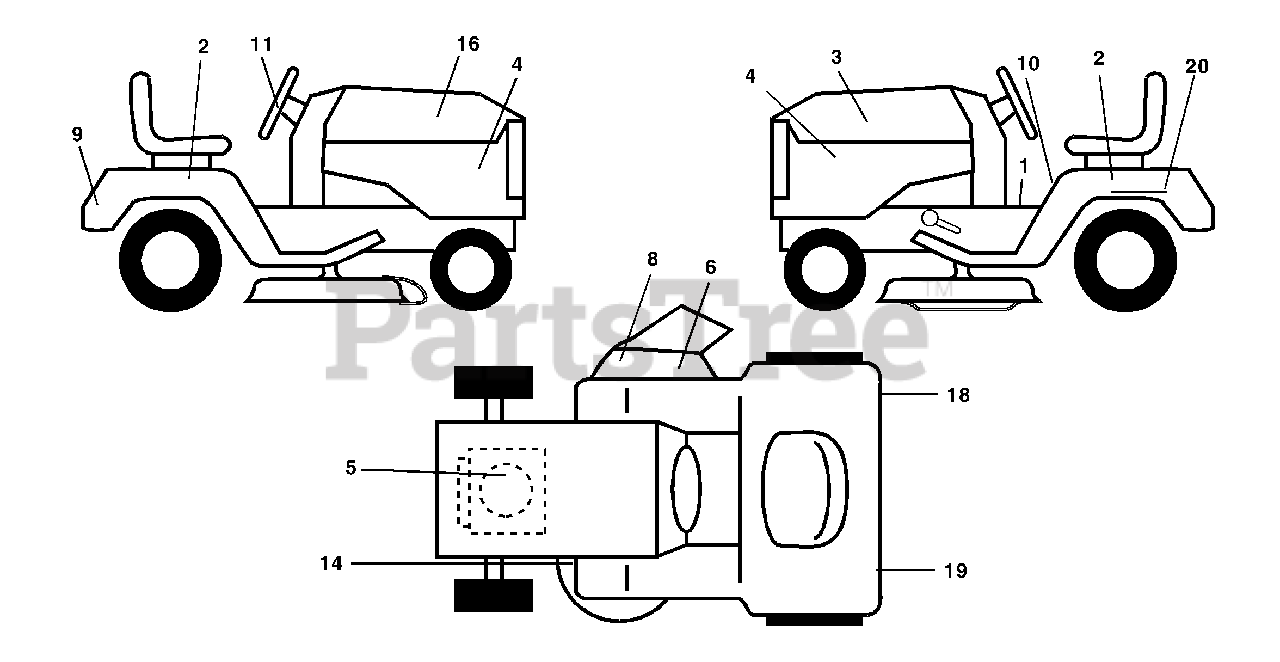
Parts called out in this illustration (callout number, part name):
2	Decal Fender Side
3	Decal Hood LH
4	Decal Side Panel Logo
5	Decal HP Engine
6	Decal Deck "B" 42"
8	Decal Warning Mult-Language
9	Decal Fender Logo
10	Decal Fender Danger E/F
11	Decal Ins Strg Whl
14	Decal V-Belt Schematic
16	Decal Hood Rh
18	Decal Fender Reflector RH
19	Decal Fender Reflector LH
20	Decal Bat Dan/Psn
